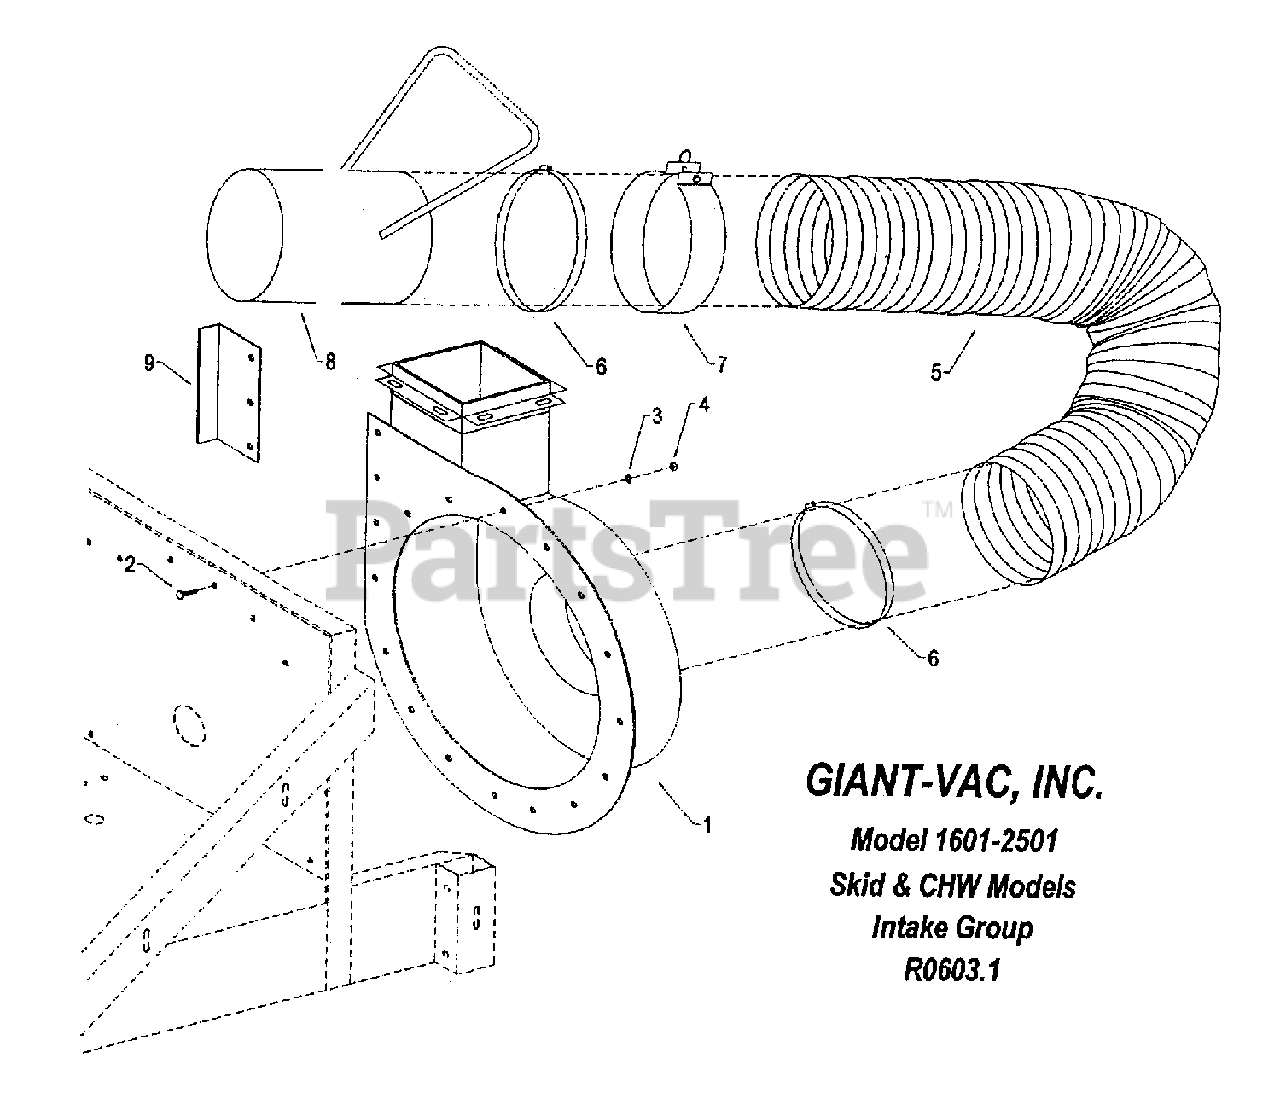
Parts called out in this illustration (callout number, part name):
1	Housing, impeller -complete with liner kit below
1	Housing, impeller- complete with liner kit below
2	Bolt, hex-3/8-16 x 1"
3	Washer, lock -3/8"
4	Nut, hex-3/8-16
5	Hose, intake -10" x 10'
5	Hose, intake -12" x 10'
6	Clamp, hose -10"
6	Clamp, hose -12"
7	Band, hose support -10" -with hardware *
7	40110 Band, hose support -12" -with hardware *
8	Nozzle, intake-10"
8	Nozzle intake -12"
9	Plate, hose protector (CHW units only)
